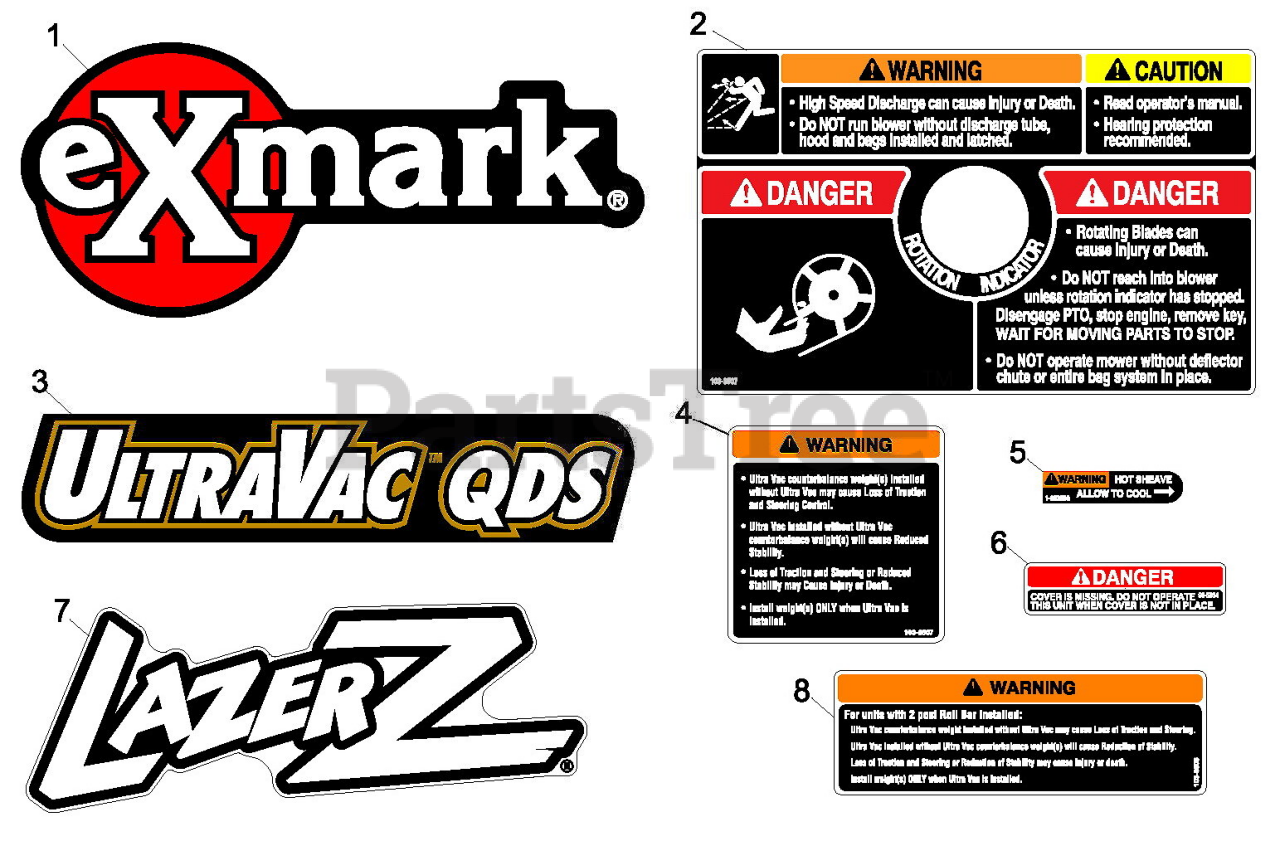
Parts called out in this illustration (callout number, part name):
1	DECAL, EXMARK
3	DECAL, ULTRAVAC QDS
4	DECAL,WEIGHT
5	DECAL-WARNING
6	DECAL-COVER, MISSING
7	DECAL,LAZER MODEL
8	DECAL,WEIGHT
